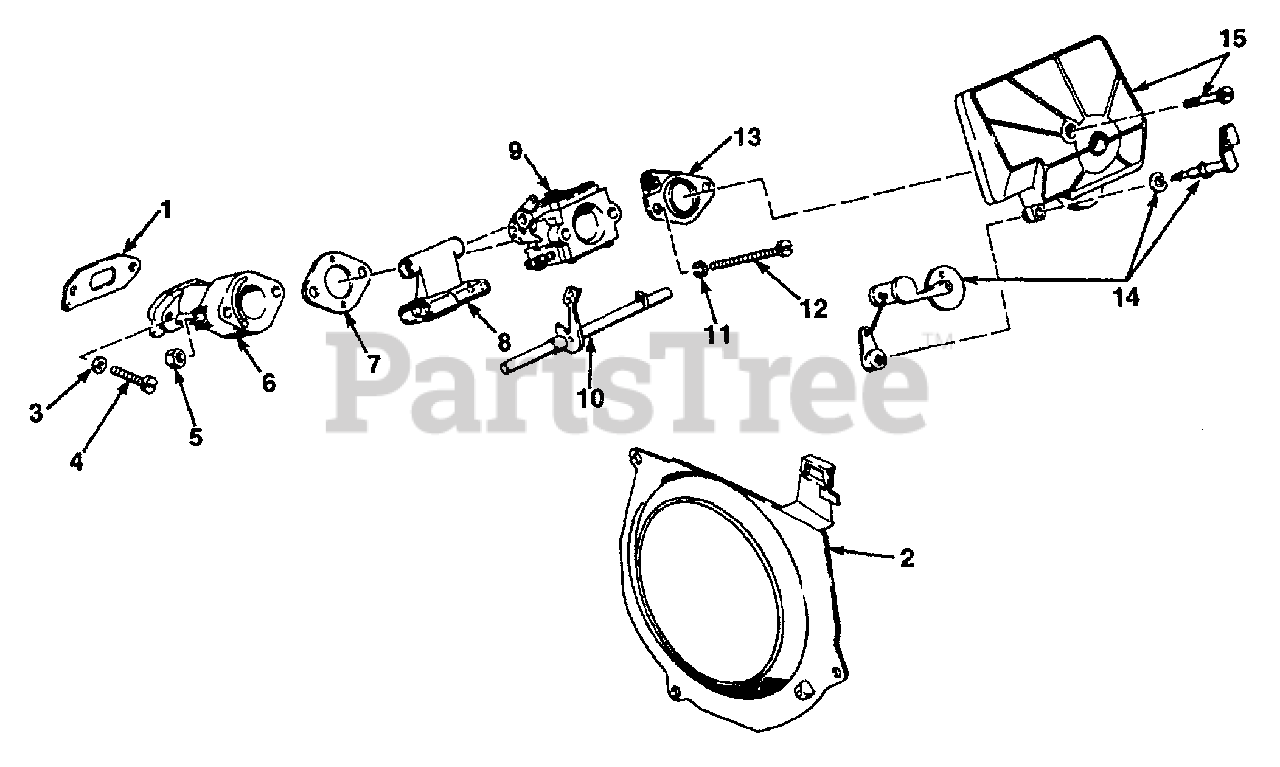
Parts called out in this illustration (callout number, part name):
1	GASKET-Intake manifold
2	GUIDE-Air
3	WASHER-Spring
4	SCREW (M5 x 20)
5	NUT (M5)
6	MANIFOLD-Intake
7	GASKET-Carburetor
8	GUIDE-Carburetor screw
9	CARBURETOR (HU63A) (Till.)
10	SHAFT-Throttle
11	WASHER-Spring
12	SCREW-(M5 x 45)
13	PLATE-Filter mounting
14	KIT-Choke lever
15	AIR FILTER ASSEMBLY
